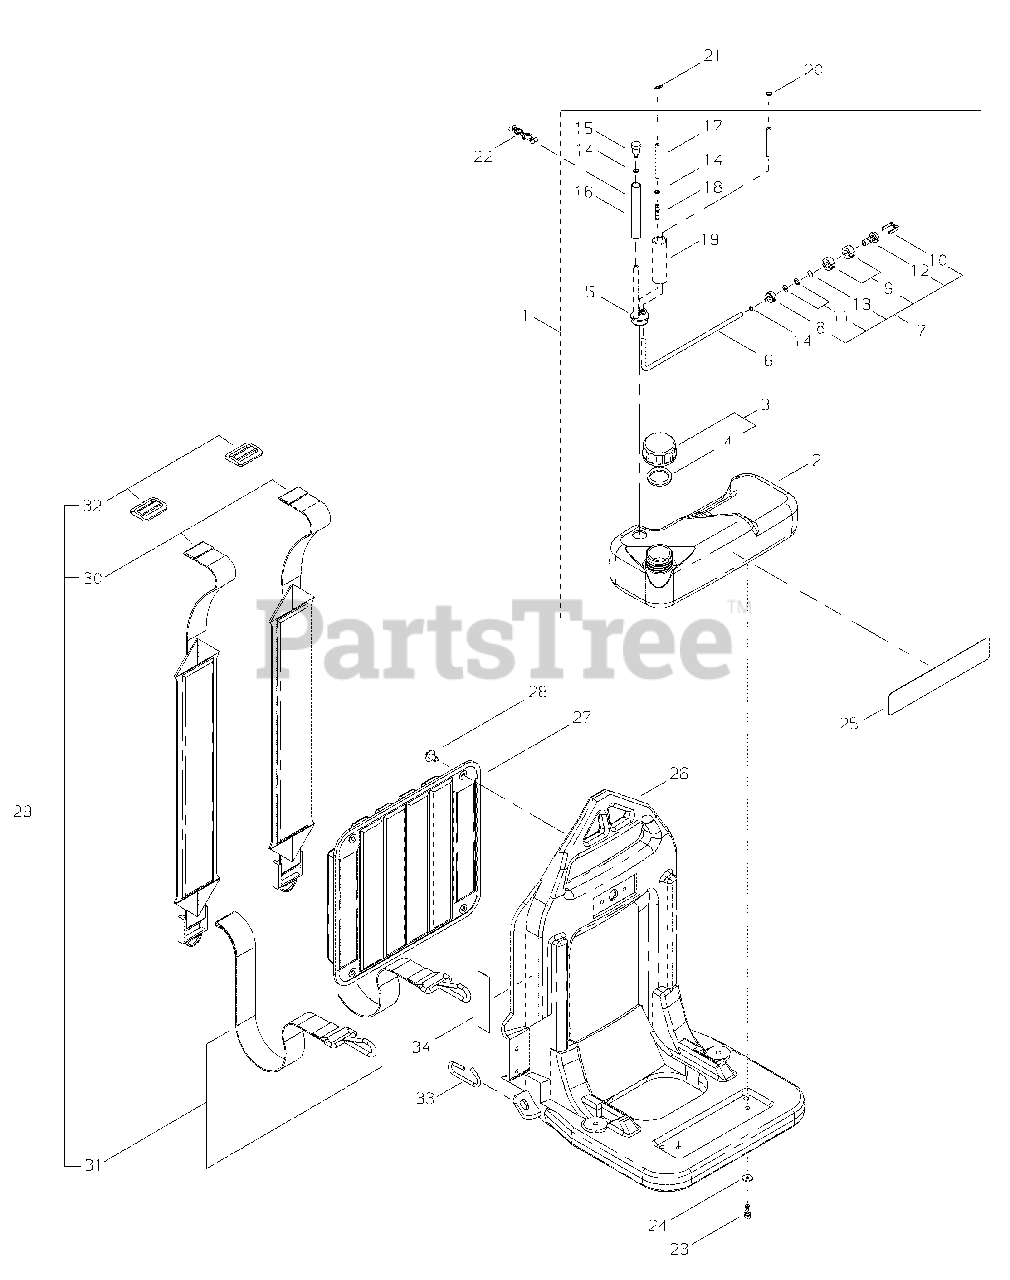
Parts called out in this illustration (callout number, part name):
1	TANK ASSY, FUEL
2	TANK, FUEL
3	CAP ASSY, FUEL
4	GASKET, FUEL CAP
5	GROMMET, FUEL W/VENT PIPE
6	PIPE, FUEL
7	FILTER, FUEL
8	WEIGHT, FUEL LINE
9	FILTER, FUEL
10	CLIP, FILTER
11	SCREEN, FILTER
12	BODY, FUEL FILTER
13	RING, RETAINING
14	CLIP Ø6
15	VENT ASSY
16	TUBE, INSULATOR
17	PIPE Ø5ר3×L110
18	CONNECTOR, PIPE
19	TUBE, INSULATOR
20	CLIP, SPRING Ø5.2
21	CLIP Ø6
22	CLIP
23	BOLT, ADHESIVE M5×14
24	WASHER Ø15ר5.2×1.6
25	LABEL, TRADE
26	FRAME, BACKPACK
27	PAD, BACKPACK
28	CLIP
29	HARNESS ASSY
30	HARNESS
31	STRAP, HARNESS
32	BUCKLE
33	RING, HARNESS
34	LABEL, CAUTION
